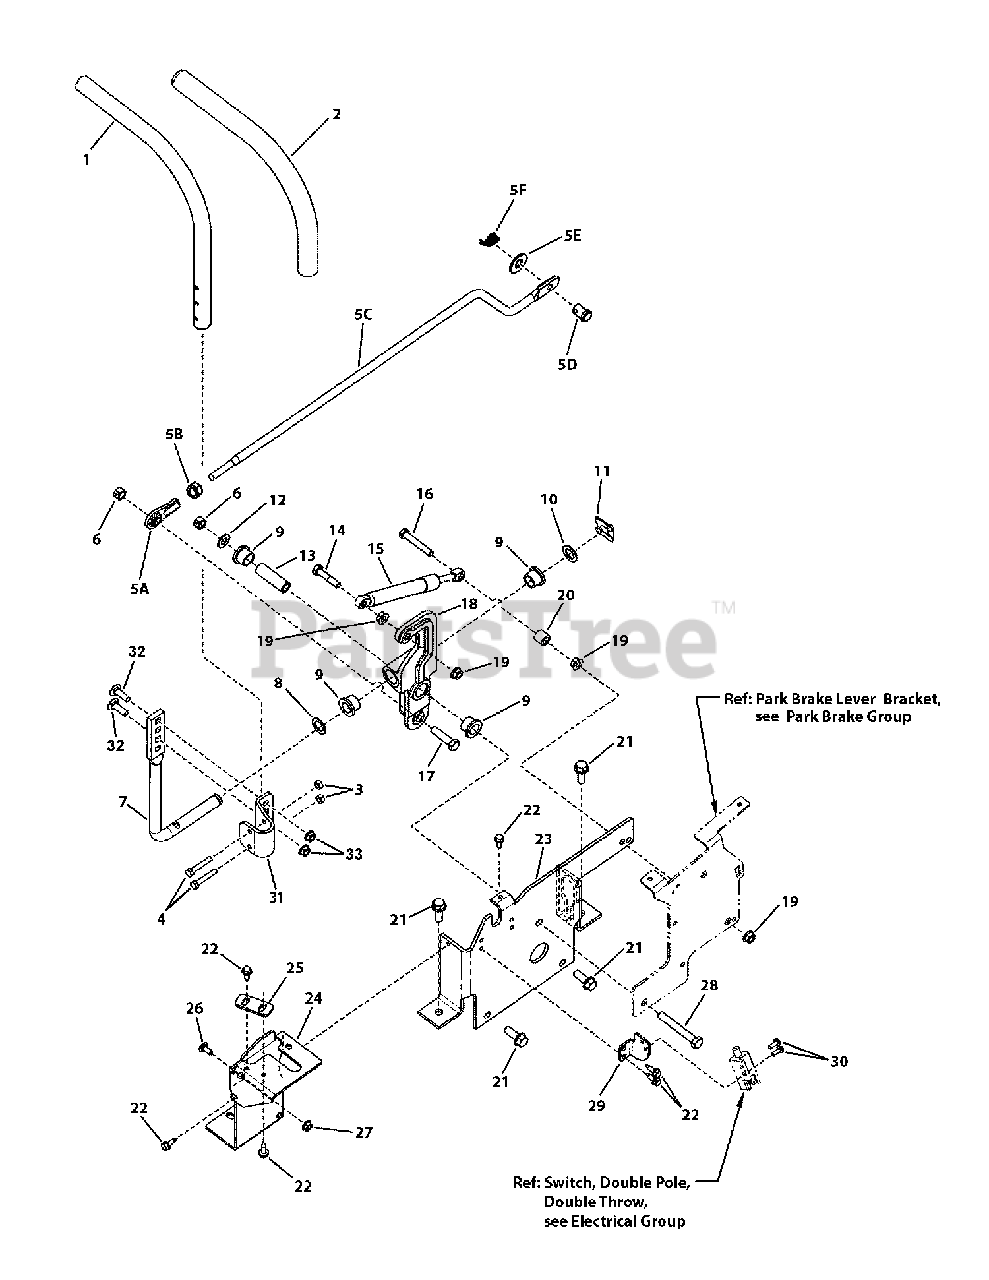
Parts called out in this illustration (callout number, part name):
1	HANDLE, Adjustable
2	GRIP, Handle
3	NUT, 1/4-20 Hex Center Lock, GR 5 BZ
4	SCREW, 1/4-20 x 1-1/2" Hex Head Cap, GR 5 BLK
5A	ROD END, (3/8-24 thread)
5B	NUT, 3/8-24 Hex, GR 5, YZ
5C	ROD, Link Forward/Reverse
5D	CLEVIS PIN, 7/16 X 1"
5E	WASHER, 7/16" Flat
5F	COTTER PIN, 1/2 Self-Locking, YZ
6	NUT, 3/8-16 Hex Center Lock, GR 5, YZ
7	ROD, Handle, Adjustable
8	WASHER, 5/8" Flat, YZ
9	BUSHING, Bronze, 5/8 x 5/8
10	WASHER, 5/8 ID. x 1" OD. x .065 Nylon
11	CLIP, Spring, 5/8 OD Shaft
12	WASHER, 3/8" Flat (SAE) YZ
13	SPACER, Sleeve, RZT
14	SCREW, 5/16-18 x 1-1/2 Hex Head Cap, GR 5, YZ
15	DAMPENER, Control
16	SCREW, 5/16-18 x 2" Hex Head Cap, GR 5
17	SCREW, 3/8-16 x 1-1/2" Hex Head Cap, GR 5, YZ
18	ARM, Control, Die Cast, LH
19	NUT, 5/16-18 Hex Flange Lock, GR 5, YZ
20	SPACER, .625 OD x .380 ID x .564 L
21	SCREW, 3/8-16 x 1" Hex Washer Self-Tap
22	SCREW, 1/4-20 x 3/4" Hex Washer Self-Tap, Black
23	BRACKET, Control, LH
24	BRACKET, Guide, Stick, Control, LH
25	PLATE, Fwd/Rev Adjust
26	BOLT, 1/4-20 x 5/8" Round Head Short Square Neck, GR 5, YZ
27	NUT, 1/4-20 Hex Flange Lock, Black
28	SCREW, 3/8-16 x 3-1/4" Hex Head Cap, GR 5, Black
29	BRACKET, Switch
30	SCREW, #10-24 x 1/2" Hex Washer Self-Tap (Torx)
31	BRACKET, Handle Adjustment
32	BOLT, 5/16-18 x 1" Round Head Square Neck, GR 5, YZ
33	NUT, 5/16-18 Hex Flange Two-Way Lk Ga
